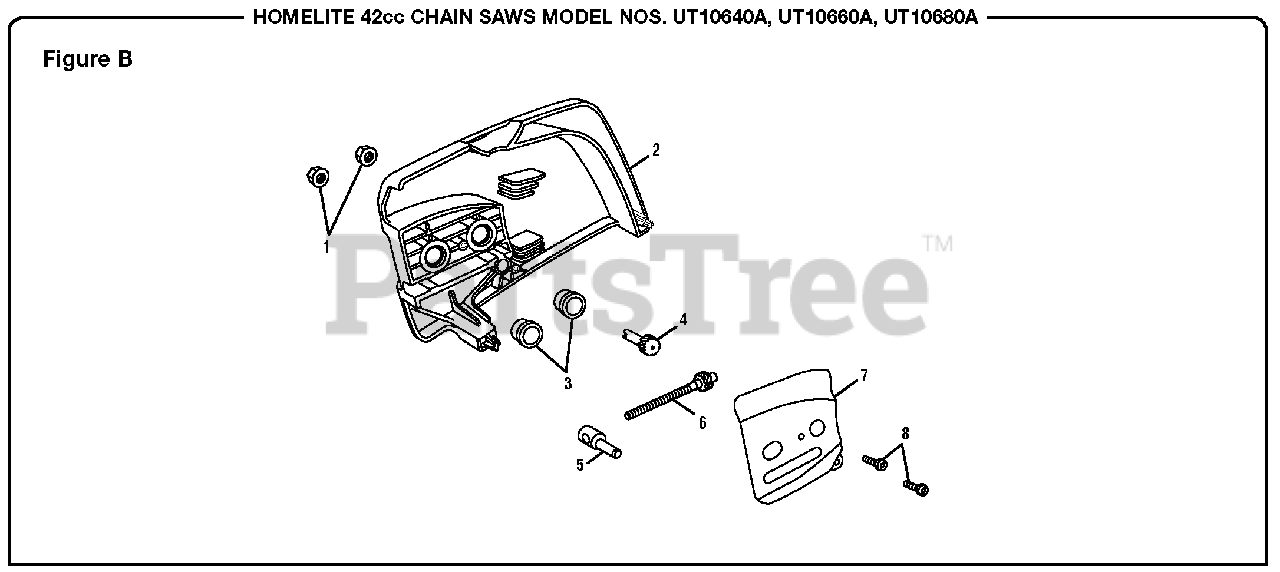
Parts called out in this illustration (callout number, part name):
1	Nut (5/16-18, Hex Hd.)
2	Clutch Cover
3	Clutch Cover Insert
4	Adjusting Gear
5	Adjusting Nut
6	Adjusting Screw
7	Guide Plate
8	Screw (M4, Torx T20)
